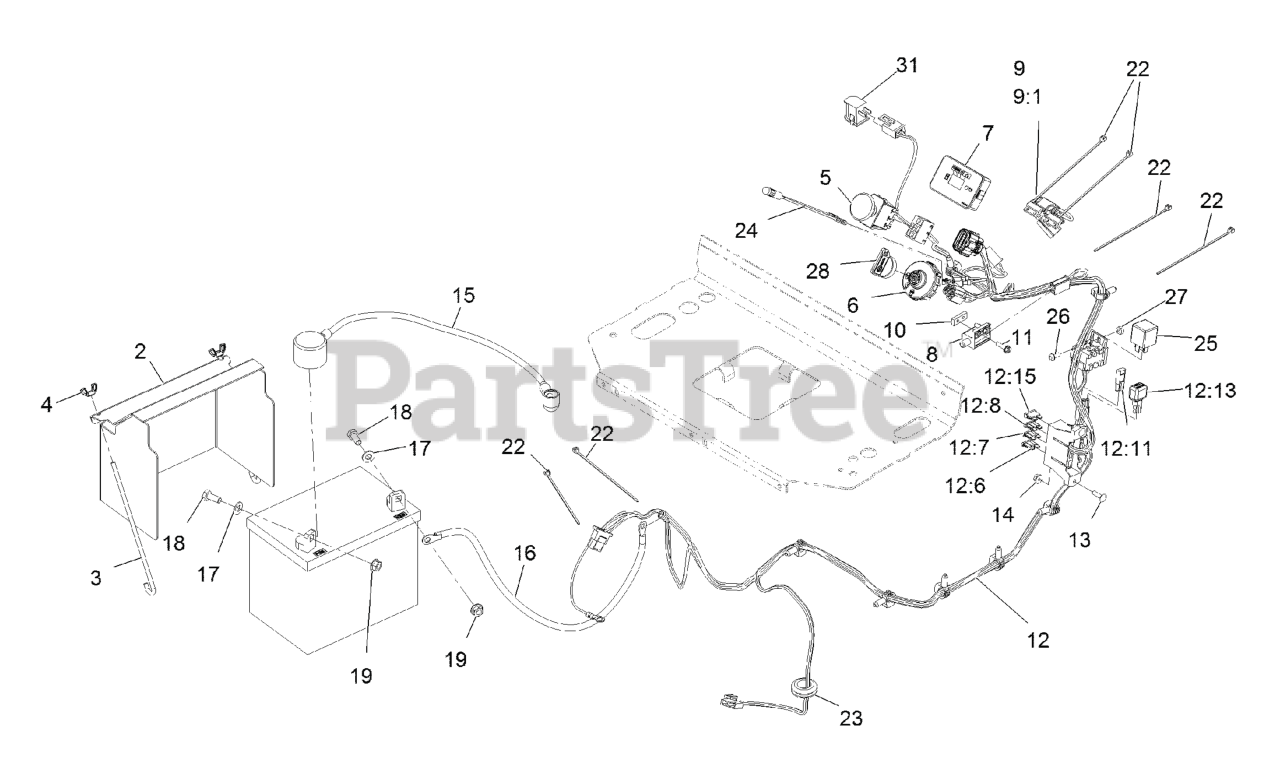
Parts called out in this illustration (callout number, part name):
2	COVER-BATTERY
3	BOLT-HOLDDOWN
4	WINGNUT
5	SWITCH-PTO, ON-ON
7	MODULE-HOUR METER
8	SWITCH-CLOSED, NORMALLY
9	HARNESS-SWITCH, REED
10	PLATE-TAPPED
11	SCREW-HWH
12	HARNESS, WIRE
12:6	FUSE-BLADE, 30 AMP
12:7	FUSE-BLADE, 25 AMP
12:8	FUSE-BLADE, 10 AMP
12:15	FUSE-BLADE, 15 AMP
13	SCREW-CARR
15	CABLE-BATTERY, POSITIVE
16	CABLE-BATTERY, BLACK
17	WASHER-PLAIN
18	SCREW-HH
19	NUT-HHF, SMOOTH
22	TIE-CABLE
23	GROMMET
24	INDICATOR-LED, RED
26	SCREW-PPH
27	NUT-LOCK, NI
28	KEY-IGNITION
31	SWITCH-BAIL
